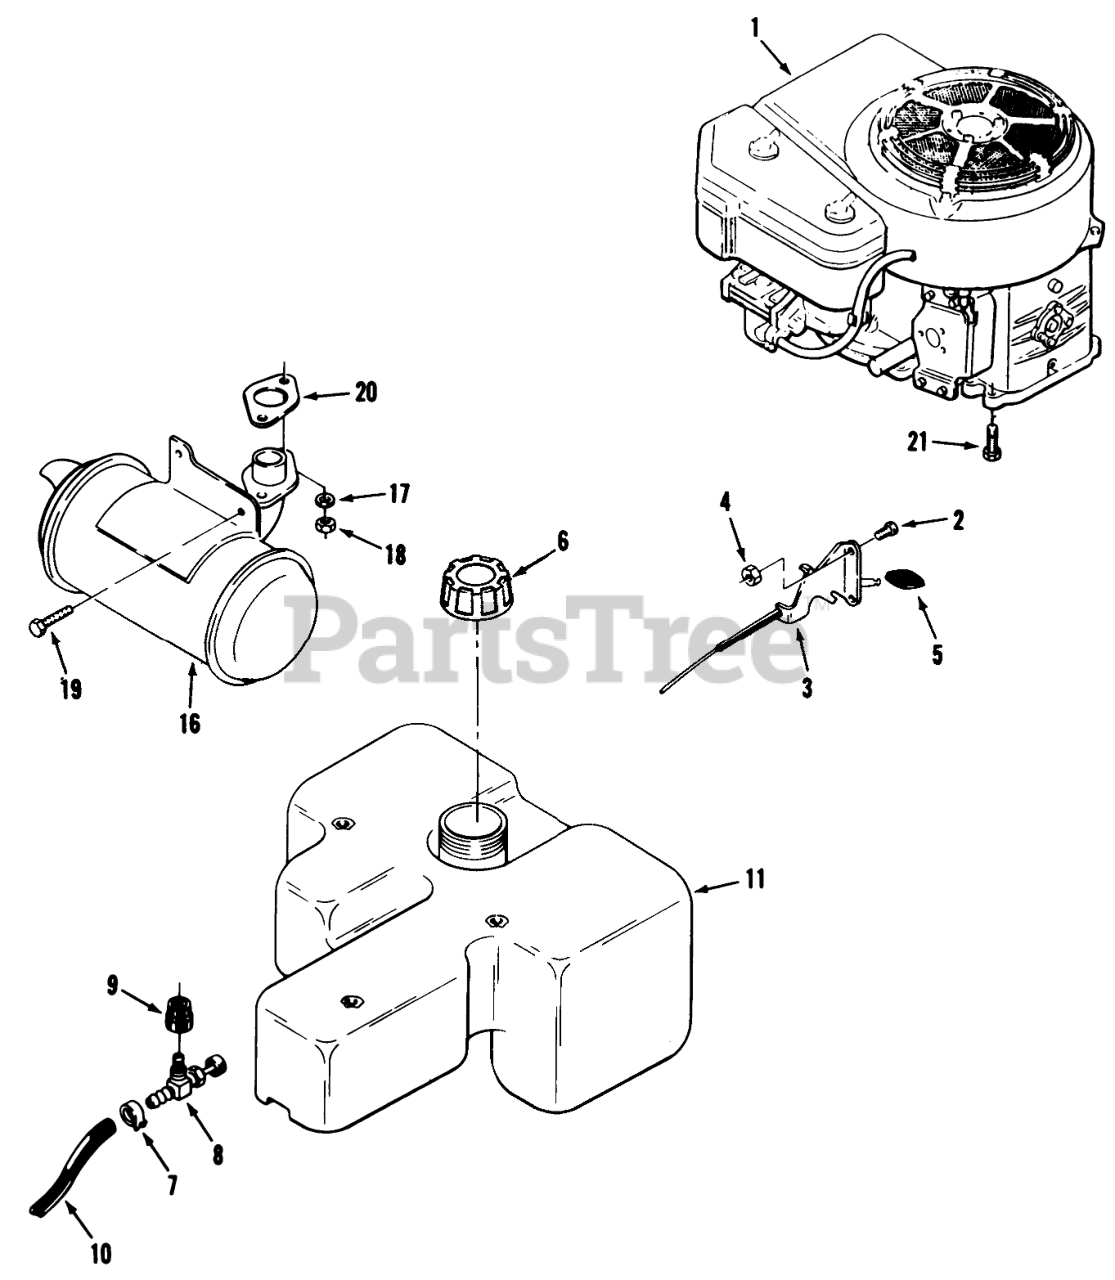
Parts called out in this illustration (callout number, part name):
1	Engine-17 HP-Kawasaki Model FC540 V K2800
2	Screw
3	THROTTLE-CONTROL
4	Nut
5	KNOB-CONTROL
6	GAS CAP ASM
7	Clamp
8	CLAMP-HOSE
9	BUSHING
10	Line-Fuel 53"
11	Fuel Tank
16	MUFFLER-EUROPE FC540
17	Lockwasher
18	NUT-HEX
19	HHCS M8X1.25X15
20	OBS GASKET-EXH FC-540V
21	BOLT M8X1.25X35MM
